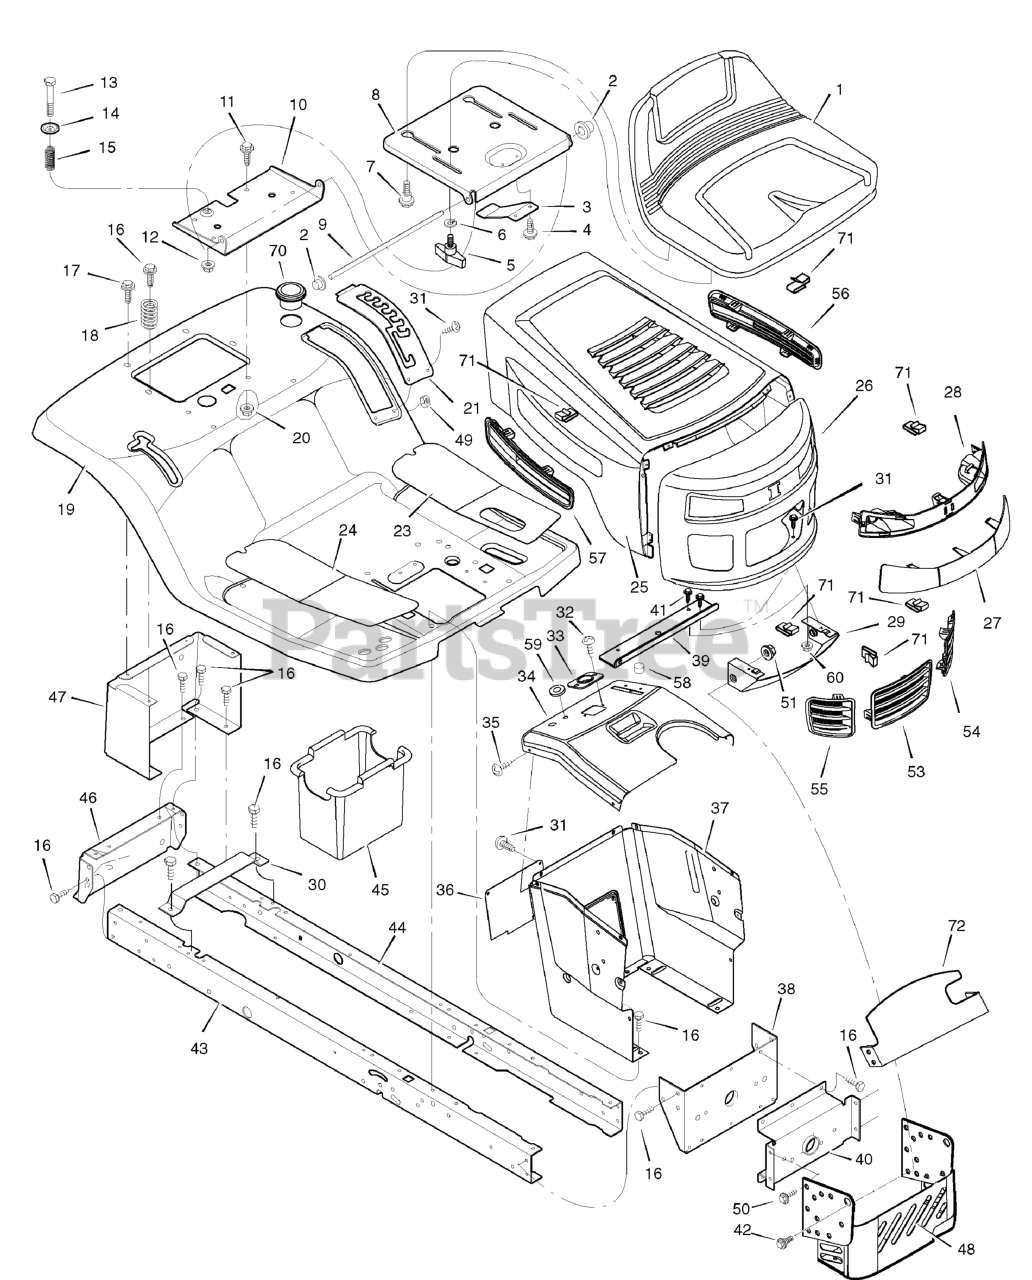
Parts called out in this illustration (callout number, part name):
1	SEAT
2	CAP, Push 0n
5	BOLT, Wing
6	WASHER
7	BOLT, Shoulder
8	SUPPORT, Seat
9	ROD, Pivot
10	BRACKET, Pivot
11	BOLT
13	BOLT, Shoulder
20	NUT
21	Plate, Index
23	MAT, Left
24	MAT, Right
26	GRILLE
28	HOUSING, Headlamp
29	BRACKET, Lower Pivot
30	SUPPORT, Battery
33	BEARING, Steering
34	DASH
36	PANEL, Access
37	SUPPORT, Dash
38	BRACKET, Rear Hanger
39	BRACKET, Support
40	AXLE, Hanger
42	BOLT, Shoulder
43	FRAME, Right
44	FRAME, Left
45	CONTAINER, Battery
46	PLATE, Hitch
47	PANEL, Rear
48	SHIELD, Heat
51	NUT
53	INSERT, Center Grille
54	INSERT, Left Grille
55	INSERT, Right Grille
56	INSERT, Left Hood
57	INSERT, Right Hood
59	GROMMET, Parking Brake
60	NUT
70	HOLDER, Cup
71	RETAINER, S-Clip
72	HEAT SHIELD, Upper
